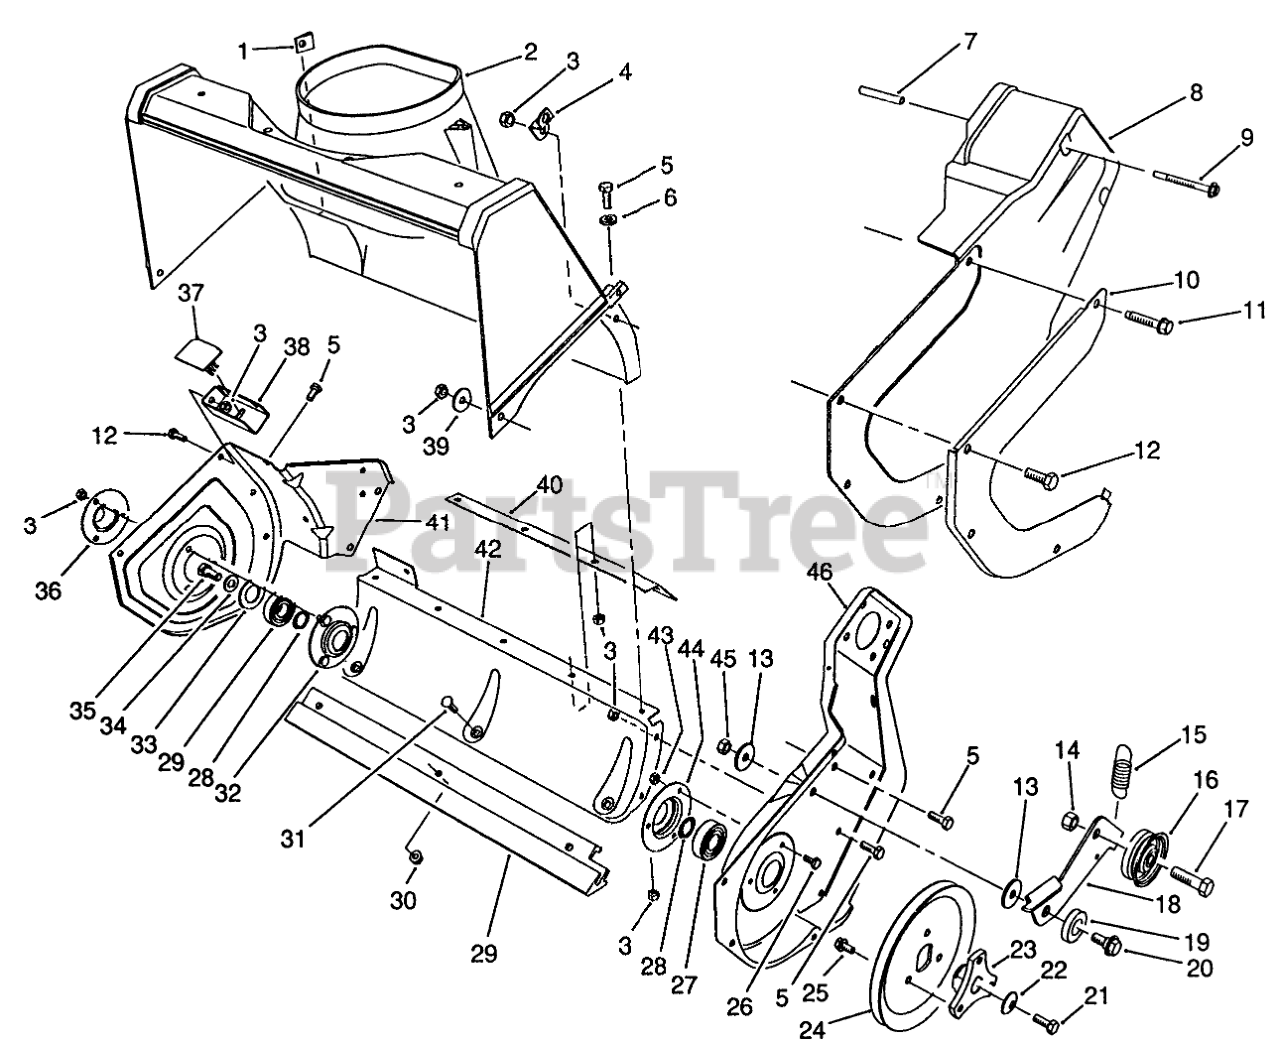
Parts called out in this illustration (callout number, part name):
1	SPEED NUT
2	HOUSING
3	NUT-LOCK, NI
4	BRACKET-HOUSING
5	SCREW-HH
6	WASHER-FLAT
7	TUBULAR SPACER
8	DRIVE COVER
9	SCREW-HWHTF
10	Guard-Drive Cover
11	SCREW-HWH, TAP
12	SCREW-HWH
13	WASHER-PIVOT
14	NUT-LOCK, NI
15	SPRING-BRAKE
16	PULLEY-IDLER
17	SCREW-HH
18	BRAKE ARM IDLER
19	PIVOT WASHER
20	SCREW-SHOULDER
21	SCREW-HH
22	WASHER-BELLEVILLE
23	HUB-MOUNTING, PULLEY
24	ROTOR PULLEY
25	SCREW
26	SCREW-SHH
27	BEARING-BALL
28	WASHER-THRUST
29	SCRAPER
30	NUT-LOCK, HHF
31	SCREW-CARR
32	FLANGE-BEARING
33	WASHER-RUBBER
34	WASHER-FLAT
35	SCREW-HHF
36	Trough
37	BRACKET COVER
38	SIDEPLATE BRKT SUPT
39	WASHER-FLAT
40	LOWER BAFFLE
41	Sideplate-R.H.
42	Housing-Lower
43	NUT-LOCK, NI
44	FLANGE-BEARING
45	NUT-LOCK, NI
46	LEFT SIDEPLATE
